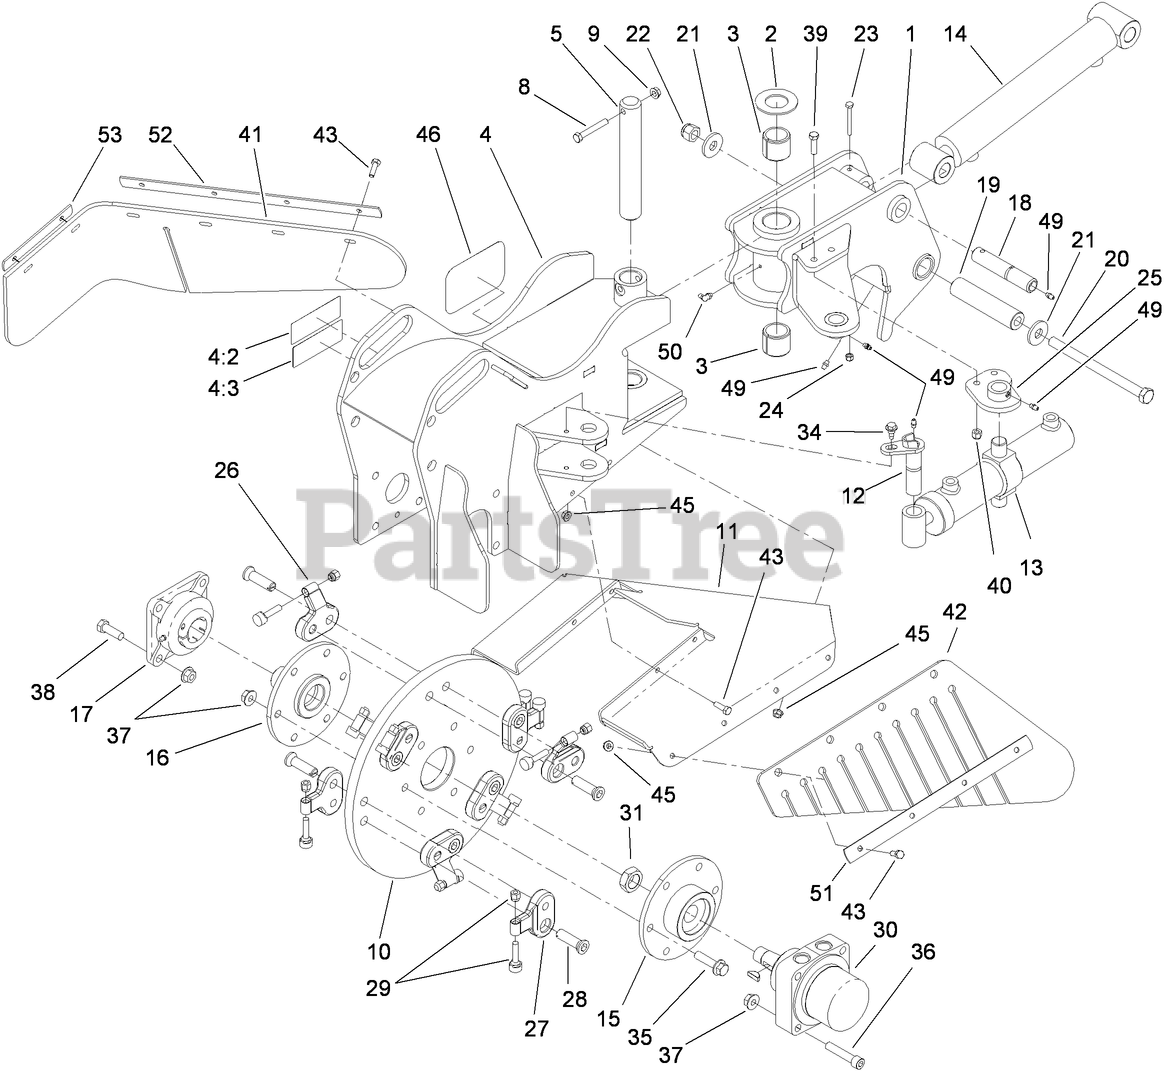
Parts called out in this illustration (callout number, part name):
2	WASHER
3	BUSHING-TENSION
4	FRAME ASM
4:2	DECAL-WARNING
4:3	DECAL-DANGER
5	PIN-PIVOT
8	SCREW-HH
9	NUT-HHF, WHIZ
10	WHEEL-CUTTER
11	GUARD-CHIP
12	PIN-PIVOT
13	HYD CYLINDER ASM
14	HYD CYLINDER ASM
15	HUB-DRIVE
16	SHAFT-STUB
17	BEARING
18	PIN-PIVOT
19	SPACER-PIVOT
20	BOLT-HH
21	WASHER-HARDENED
22	NUT-LOCK, NI
23	SCREW-HH
24	NUT-LOCK, NI
25	MOUNT-CYLINDER
26	POCKET-ANGLED
27	POCKET-STRAIGHT
28	BOLT-HSH, RH
29	GRINDER TOOTH ASM
30	HYD MOTOR ASM
31	NUT-LOCK
34	BOLT-SHOULDER
35	SCREW-HHF
36	SCREW-HSH
37	NUT-HHF
38	SCREW-HH
39	SCREW-HH
40	NUT-LOCK, NI
41	SHIELD-RUBBER, RH
42	SHIELD-RUBBER, LH
43	SCREW-HH
45	NUT-LOCK, NI
49	FITTING-GREASE
50	FITTING-GREASE, 90 DEG
51	STRAP-RETAINER, LH
52	STRAP-RETAINER, REAR
53	STRAP-RETAINER, RH
